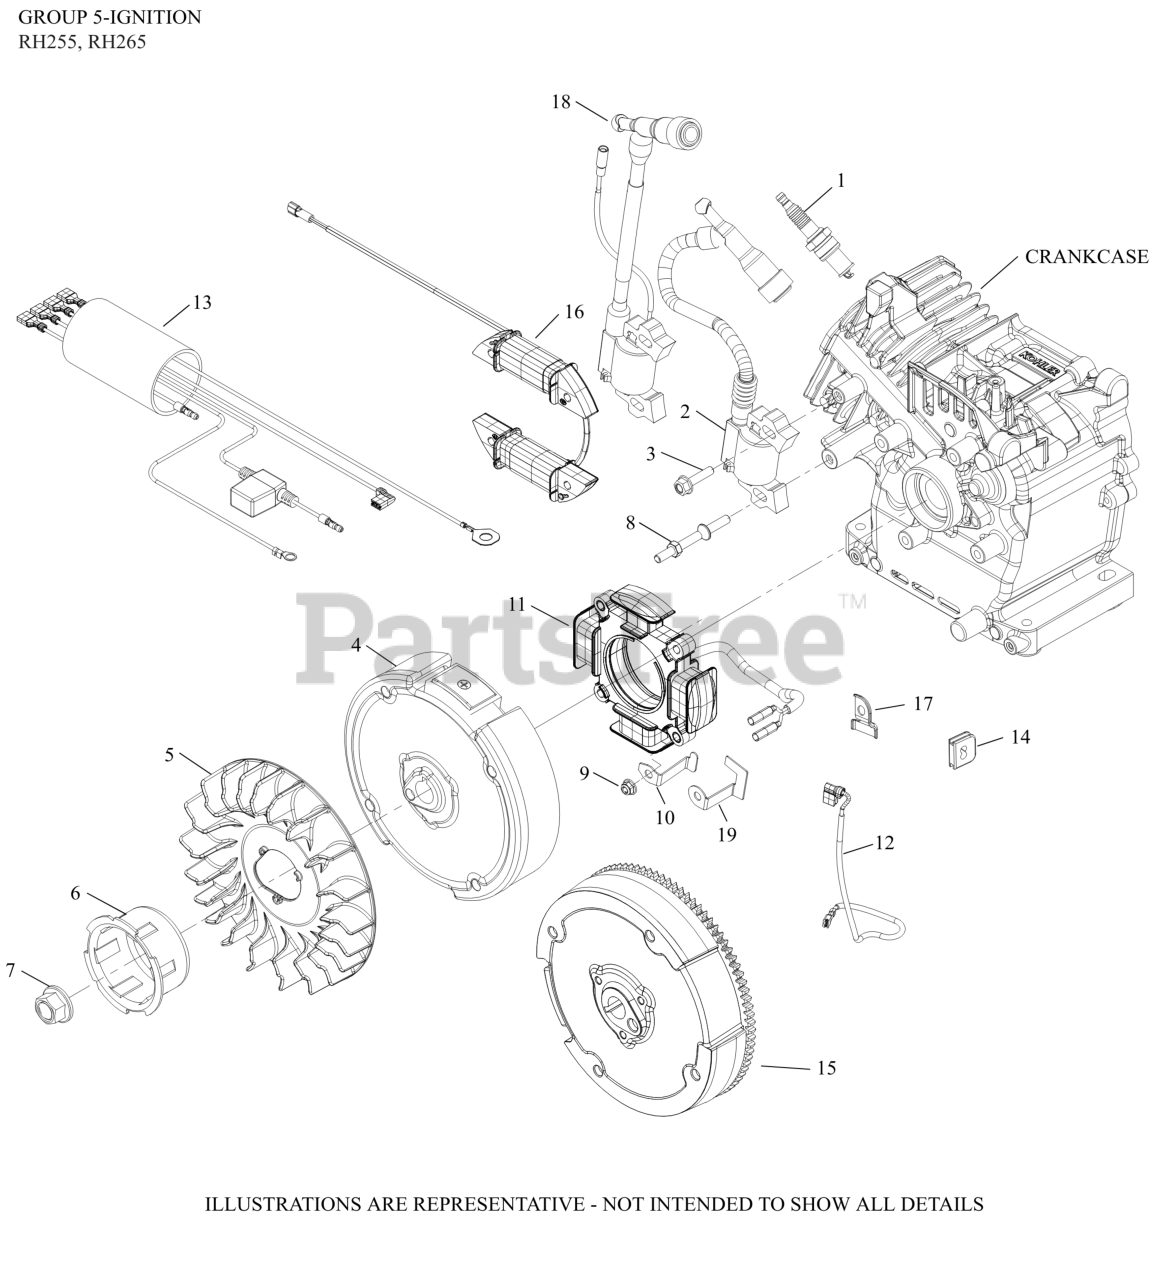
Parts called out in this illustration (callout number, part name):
1	PLUG SPARK 12MM RFI
2	MODULE, IGNITION
3	SCREW, M6 X 25-(#25086436S)
4	FLYWHEEL ASSEMBLY
5	FAN, FLYWHEEL
6	CUP, STARTER DRIVE
7	NUT, FLYWHEEL (W/SERRATIONS)
8	STUD, IGNITION MODULE
